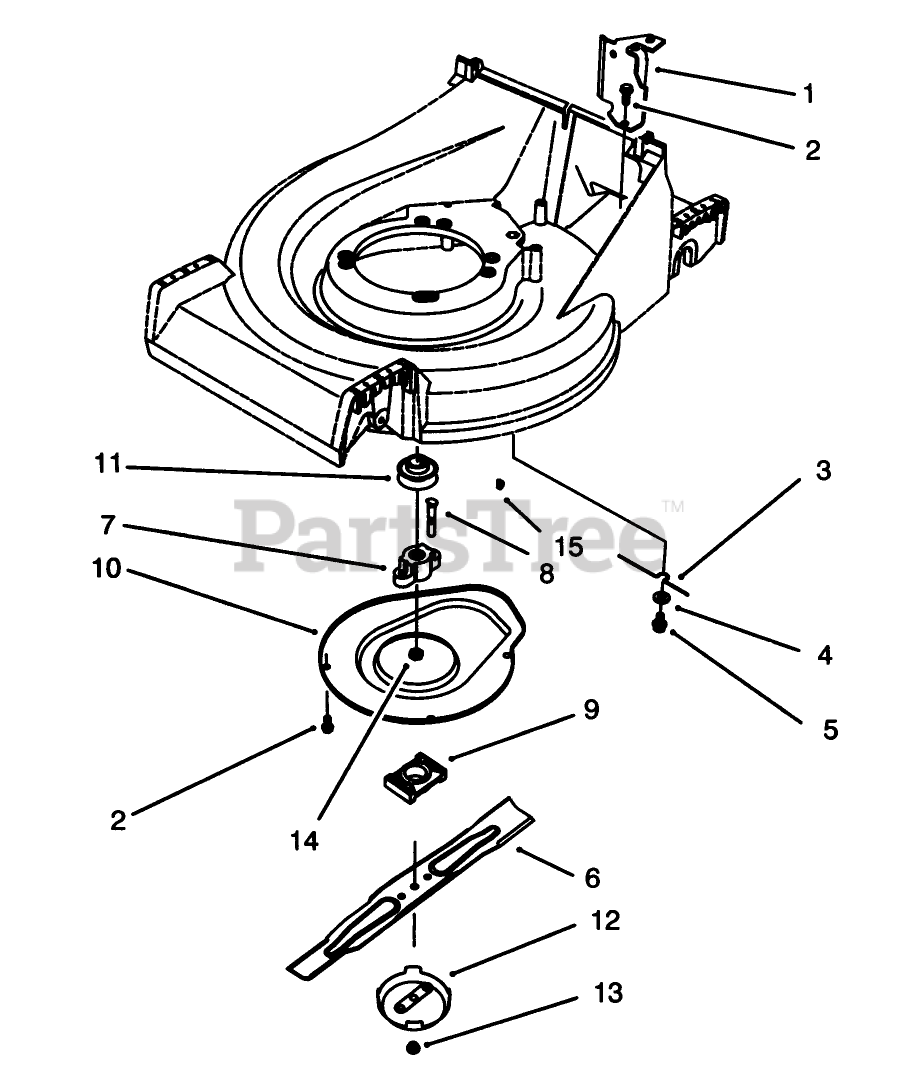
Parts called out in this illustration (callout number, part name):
2	SCREW-HWHTF
3	RETAINER-BELT
4	WASHER-FLAT
5	SCREW-HHFTF
8	BOLT-BLADE
11	PULLEY
12	CUP-SCALP, ANTI
13	NUT-LOCK
14	NUT-LOCK, NI
15	KEY-WOODRUFF
